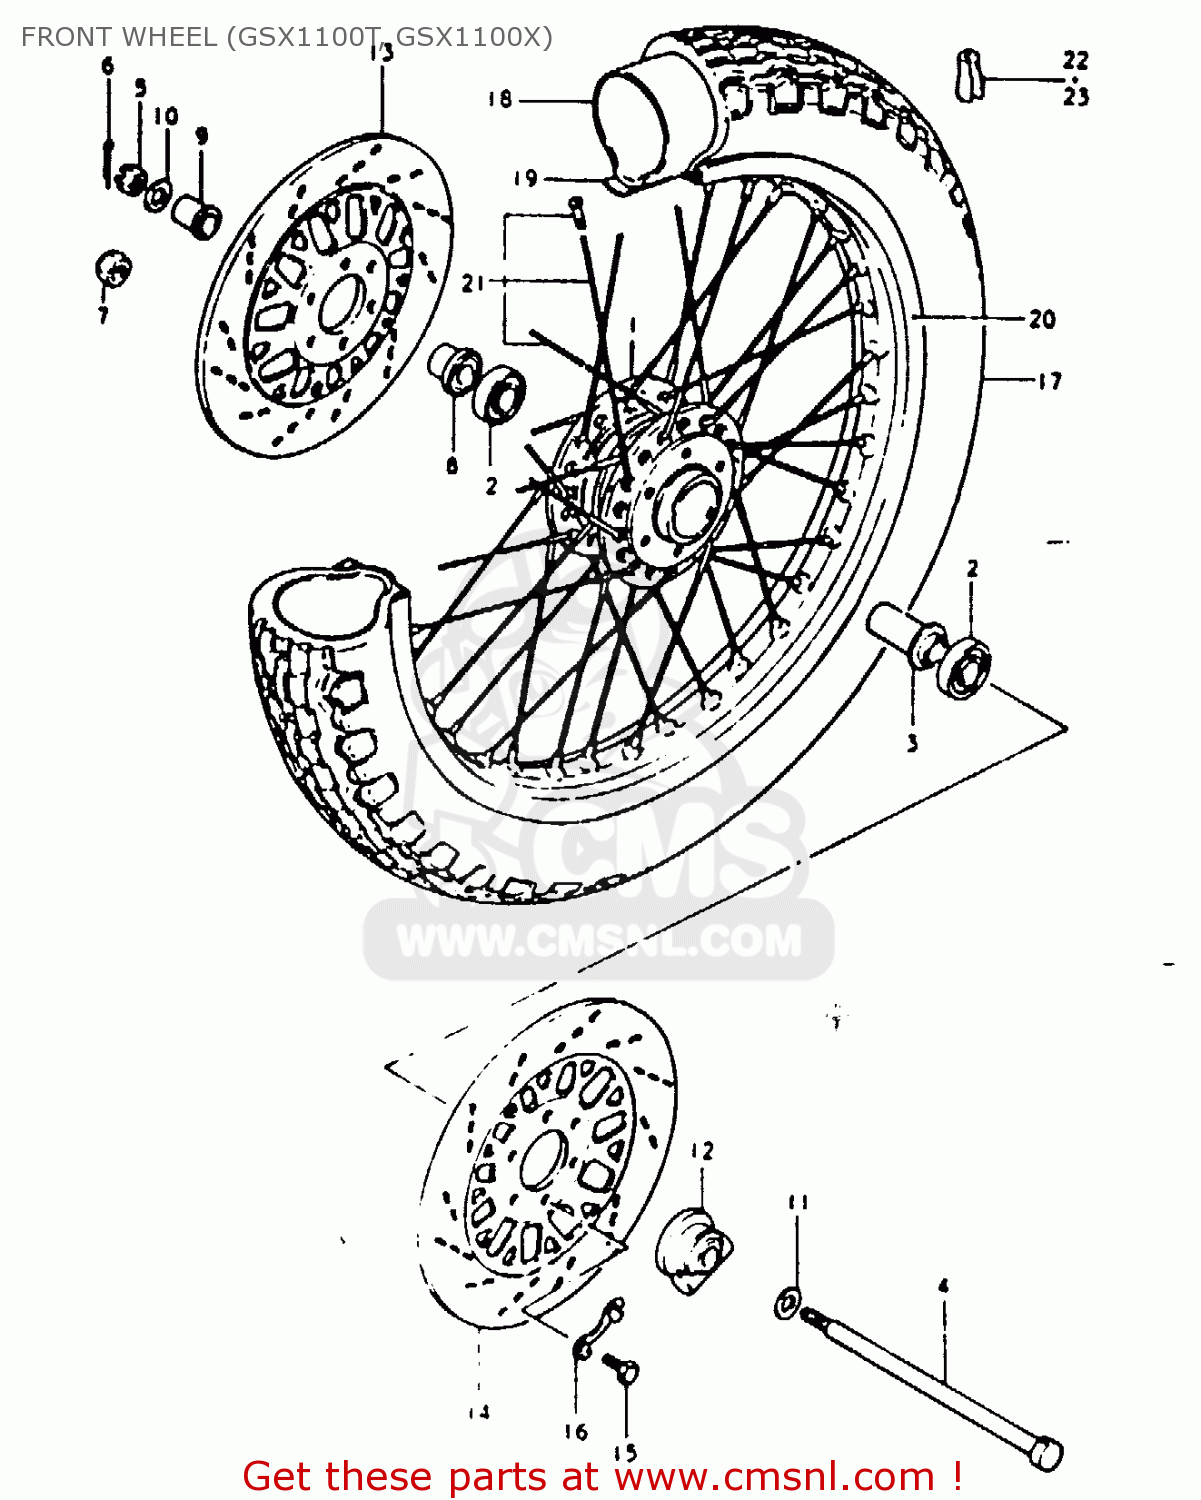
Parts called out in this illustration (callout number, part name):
1	DRUM,FRONT HUB
2	BEARING
3	SPACER,FR HUB BEARING
4	AXLE,FR
5	NUT 12MM
6	COTTER PIN
8	SPACER,FR AXLE,R
9	SPACER
10	WASHER
11	WASHER(15.5X26X2.3)
12	BOX ASSY,SPEEDOMETER GEAR
13	DISC,FR BRAKE,R
14	DISC,FR BRAKE,L
15	BOLT(8X25)
16	WASHER
17	TIRE (3.50V19)
18	TUBE,INNER
19	PROTECTOR,WHL INR TUBE
20	RIM,FRONT WHEEL
21	SPOKE SET,FRONT
22	BALANCER,WHEEL (B)
23	BALANCER,WHEEL (30G)
